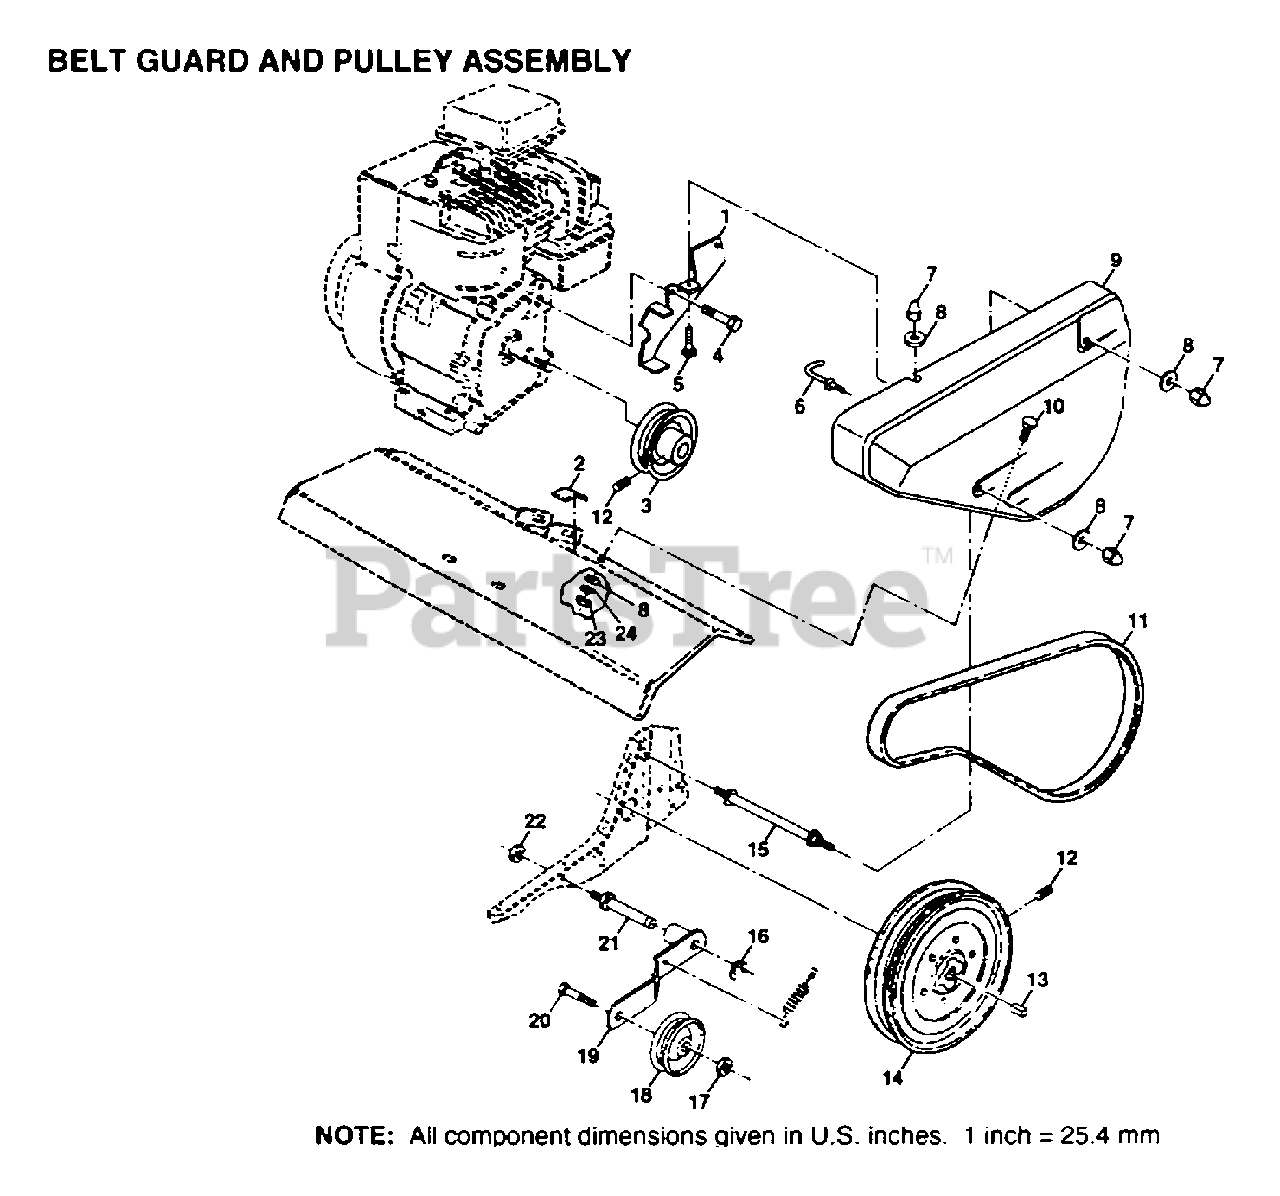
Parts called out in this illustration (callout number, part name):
2	PAD IDLER TI
3	ENGINE PULLEY
5	BOLT
6	KEEPER, BELT
7	NUT-CAP TI
8	WASHER
9	GUARD.BELT
10	BOLT T
11	V BELT STD
12	SET SCREW
13	KEY T
14	TRANS SHEAVE RT
15	BOLT TI
16	KLIP RING TI
17	NUT
19	IDLER ARM TI
21	SHAFT IDLER TI
22	JAM NUT TI
24	LOCKWASHER
